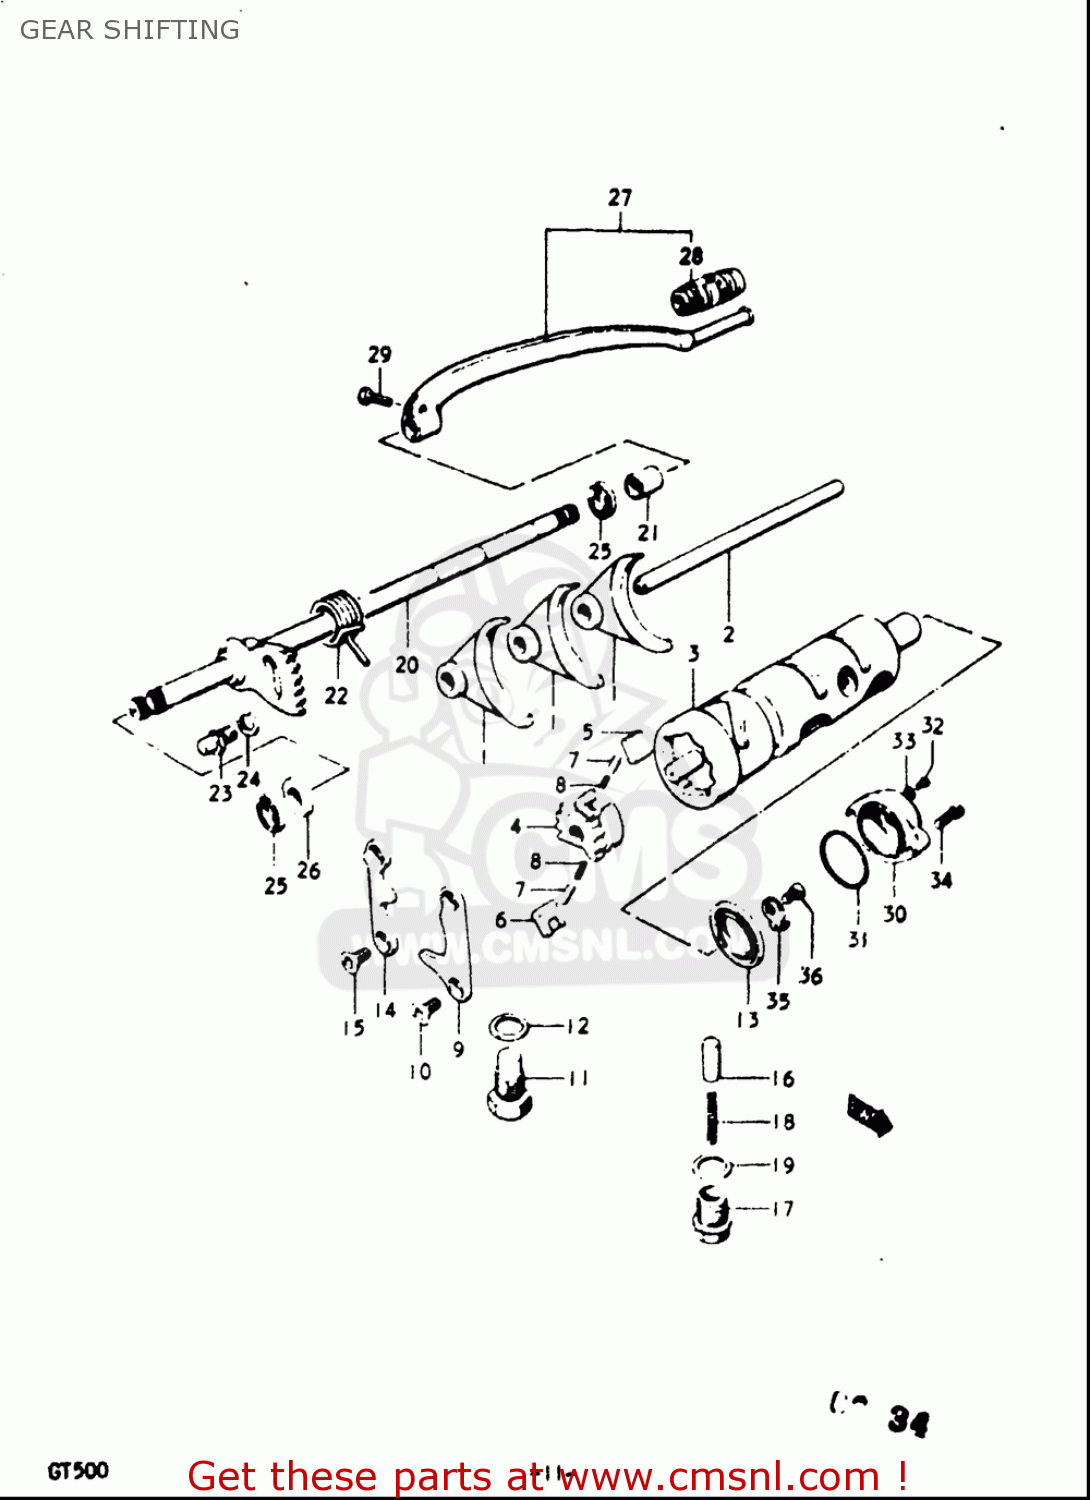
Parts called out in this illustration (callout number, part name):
4	GEAR,GEAR SHIFT CAM DRIVEN
5	PAWL,GEAR SHIFT NO.1
6	PAWL,GEAR SHIFT NO.2
7	PIN(5X8)
8	SPRING
9	LIFTER,GEAR SHIFT PAWL
10	SCREW
11	BOLT
12	GASKET(14X19.2X2) (NAS)
13	SEAL,OIL(16X30X8)
14	GUIDE,GEAR SHIFT
15	SCREW
16	STOPPER,REVERSE CAM
17	HOUSING,GEAR SHIFT CAM STOPPER
18	SPRING
19	GASKET(14X19.2X2) (NAS)
22	SPRING
23	STOPPER,GEAR SHIFT ARM
24	WASHER,LOCK
25	SEAL,OIL (12X22X9)
26	CUSHION
27	LEVER ASSEMBLY,GEAR SHIFTING
28	RUBBER,GEAR SHIFT PEDAL
29	BOLT
30	BODY,GEAR SHIFT SWITCH
31	O RING(D:1.9,ID:27.7)
32	SCREW
33	WASHER
34	SCREW
35	CONTACT,GEAR SHIFT SWITCH
36	SCREW
